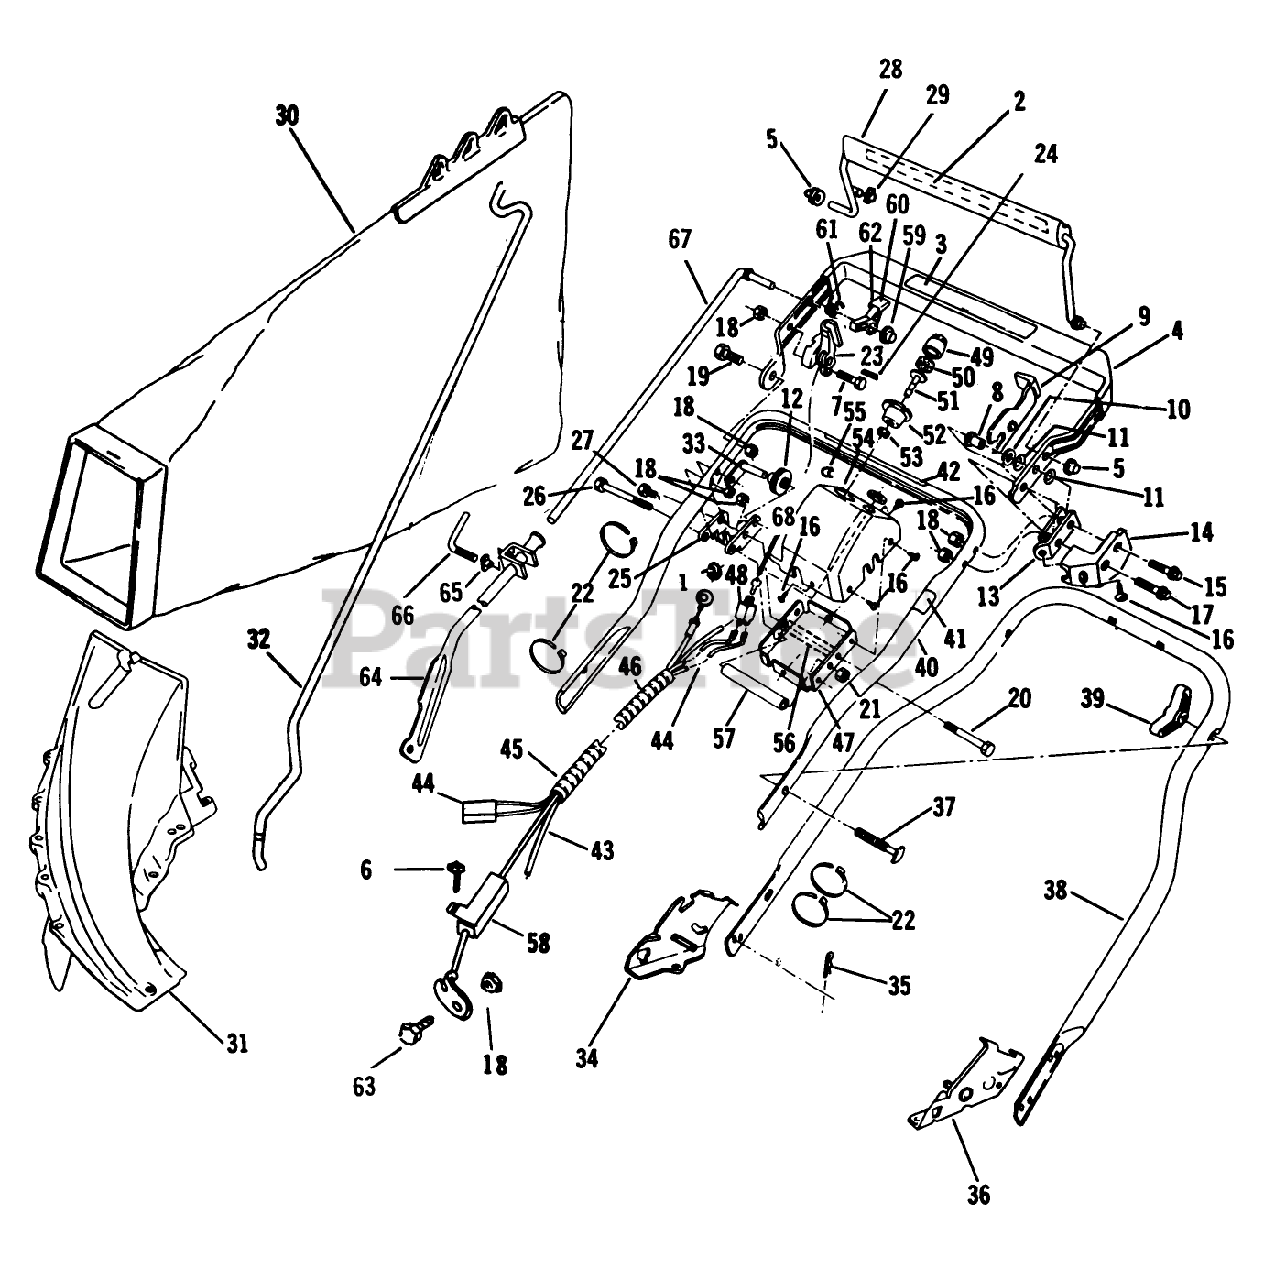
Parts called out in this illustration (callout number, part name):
1	RET. RING
6	SCREW-HH
8	SPACER
10	WASHER M
13	DOWN STOP
14	LOCKOUT GUARD
15	BOLT SHOU
16	SCREW F
17	SCREW
18	LOCKNUT E
19	BOLT
23	CAM (12)
26	BOLT-CONSOLE
29	NUT ACORN
30	89802 LB WHOLE GOODS
32	ROD GRASSBAG
34	BRACKET ASM - HANDLE, SP, RH
35	HAIR PIN
36	BRACKET ASM - HANDLE, SP, LH
37	BOLT QUALITY
39	NUT-WING
48	SWITCH AY
50	FILTER S
53	LOCKNUT S
56	SPACER
58	CONTROL CABLE
